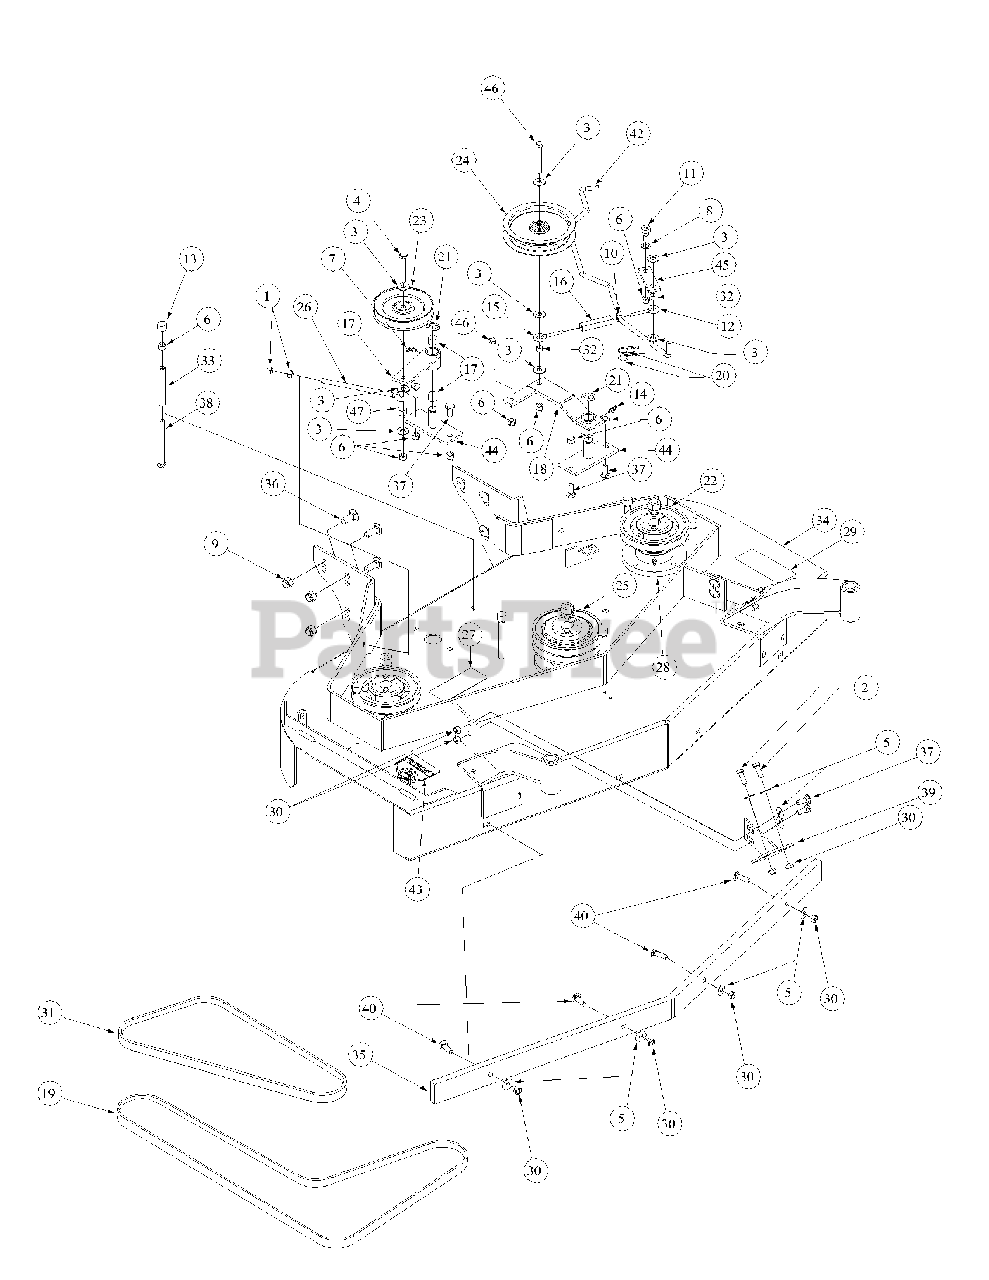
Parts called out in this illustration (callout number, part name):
1	Hex Nut, 3/8-16
2	Hex Cap Screw, 3/8-16, 1
3	Flat Washer, 3/8 Zinc
4	Hex Cap Screw, 3/8-16, 1
5	Flat Washer, 3/8 Zinc
6	Lock Nut, Nylon Insert, 3/8-16
7	Grease Fitting, 1/4-28, 90°.
8	Shim Washer
9	Lock Nut, Nylon Insert, 1/2-13
10	Hex Nut, 5/16-18
11	Shoulder Bolt
12	Eye Bolt, Right Hand
13	Vinyl Cap
14	Grease Fitting, 1/4-28, 45°.
15	Eye Bolt, Left Hand
16	Turnbuckle
17	Idler Arm "B"
18	Idler Arm "A"
19	Drive Belt
20	Hair Pin, 3/8"-1/2"
22	Deck Pulley
23	Idler Pulley
24	Idler Deck Take-up
25	Double Pulley
26	Rod Belt Tensioner
27	Decal Rotating Blade
28	Spindle Backing Plate
29	Decal Warning Shield Missing
30	Lock Nut, Metal, 3/8-16
31	Drive Belt
32	Sleve Turnbuckle
33	Spacer Belt Guide
34	Deck Weldment Mower
36	Carriage Bolt, 1/2-13 x 1-1/4
37	Carriage Bolt, 3/8-16 x 2
38	Carriage Bolt, 3/8-16 x 4-1/2
39	Caster Support Assembly
40	Carriage Screw, 3/8-16 x 1-1/4
42	Rod Clutch Link
43	Decal, Danger Hands and Feet
44	Idler Base
46	Hex Cap Screw, 3/8-16, 2.75
47	Sleeve Tensioner
